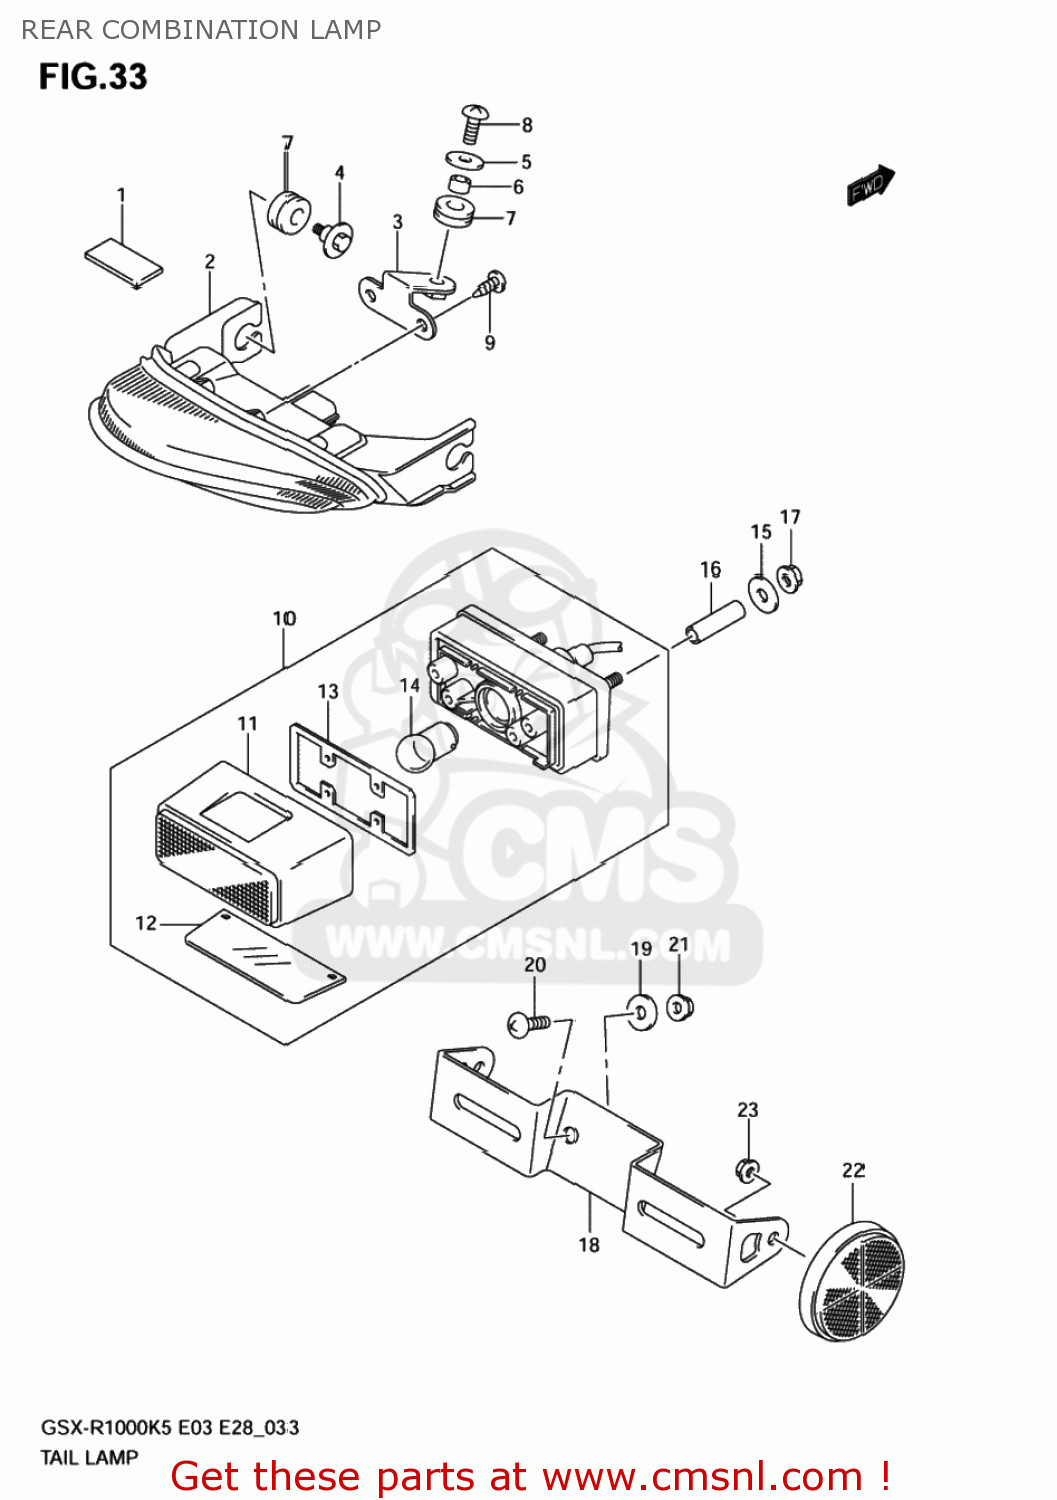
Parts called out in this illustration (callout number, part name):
1	PROTECTOR(170X95X3.0)
2	LAMP ASSY,RR COMBINATION
3	BRACKET,RR COMBINATION LAMP
4	SCREW(5X16.2)
5	WASHER(6.5X20X1.2)
6	SPACER(6.5X10X9.4)
7	CUSHION
8	SCREW
9	SCREW
10	LAMP ASSY,LICE
11	COVER,LICENSE LAMP
12	LENS LICENCE
13	GASKET (NAS)
14	BULB(12V5W,BF150-40160A)
15	WASHER(6.5X20X1.2)
16	SPACER(6.5X9X33.3)
17	NUT
18	BRACKET,LICENSE PLATE
19	WASHER(6.5X20X1.2)
20	SCREW
21	NUT
22	REFLECTOR ASSY,RR SIDE
23	NUT
